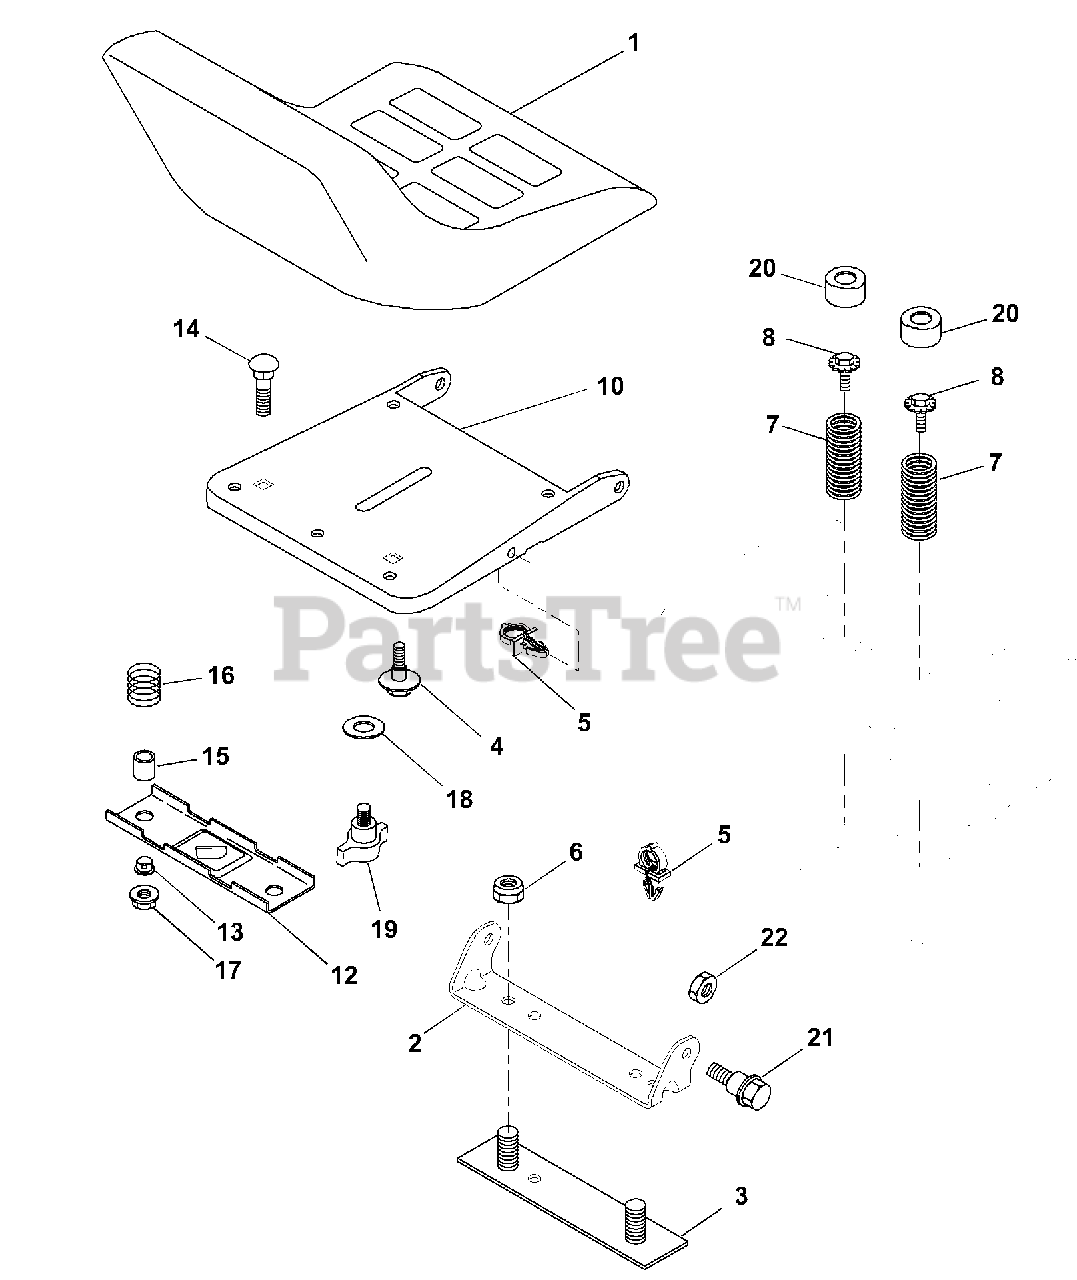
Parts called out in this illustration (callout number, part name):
1	Seat
2	Bracket, Pivot Seat
3	Strap, Fender
4	Bolt, Shoulder 5/16-18 X .62
5	Clip, Push In Hinged
6	Nut, Lock Hex W/Ins. 3/8-16 Unc
7	Spring, Seat Cprsn
8	Bolt 5/16-18unc x 3/4 W/Sems
10	Pan, Seat
12	Bracket, Mounting Switch
13	Bushing, Snap
14	Bolt, Carriage 1/4-20 X 1-1/2
15	Spacer, Split
16	Spring, Cprsn
17	Nut, Lock 1/4 Lge Flg Gr. 5
18	Washer 17/32 X 1-3/16 X 12 Ga.
19	Knob, Seat
20	Cap, Spring Seat
21	Bolt, Shoulder 5/16-18 Unc-2A
22	Nut, Crownlock 5/16-18 Unc
